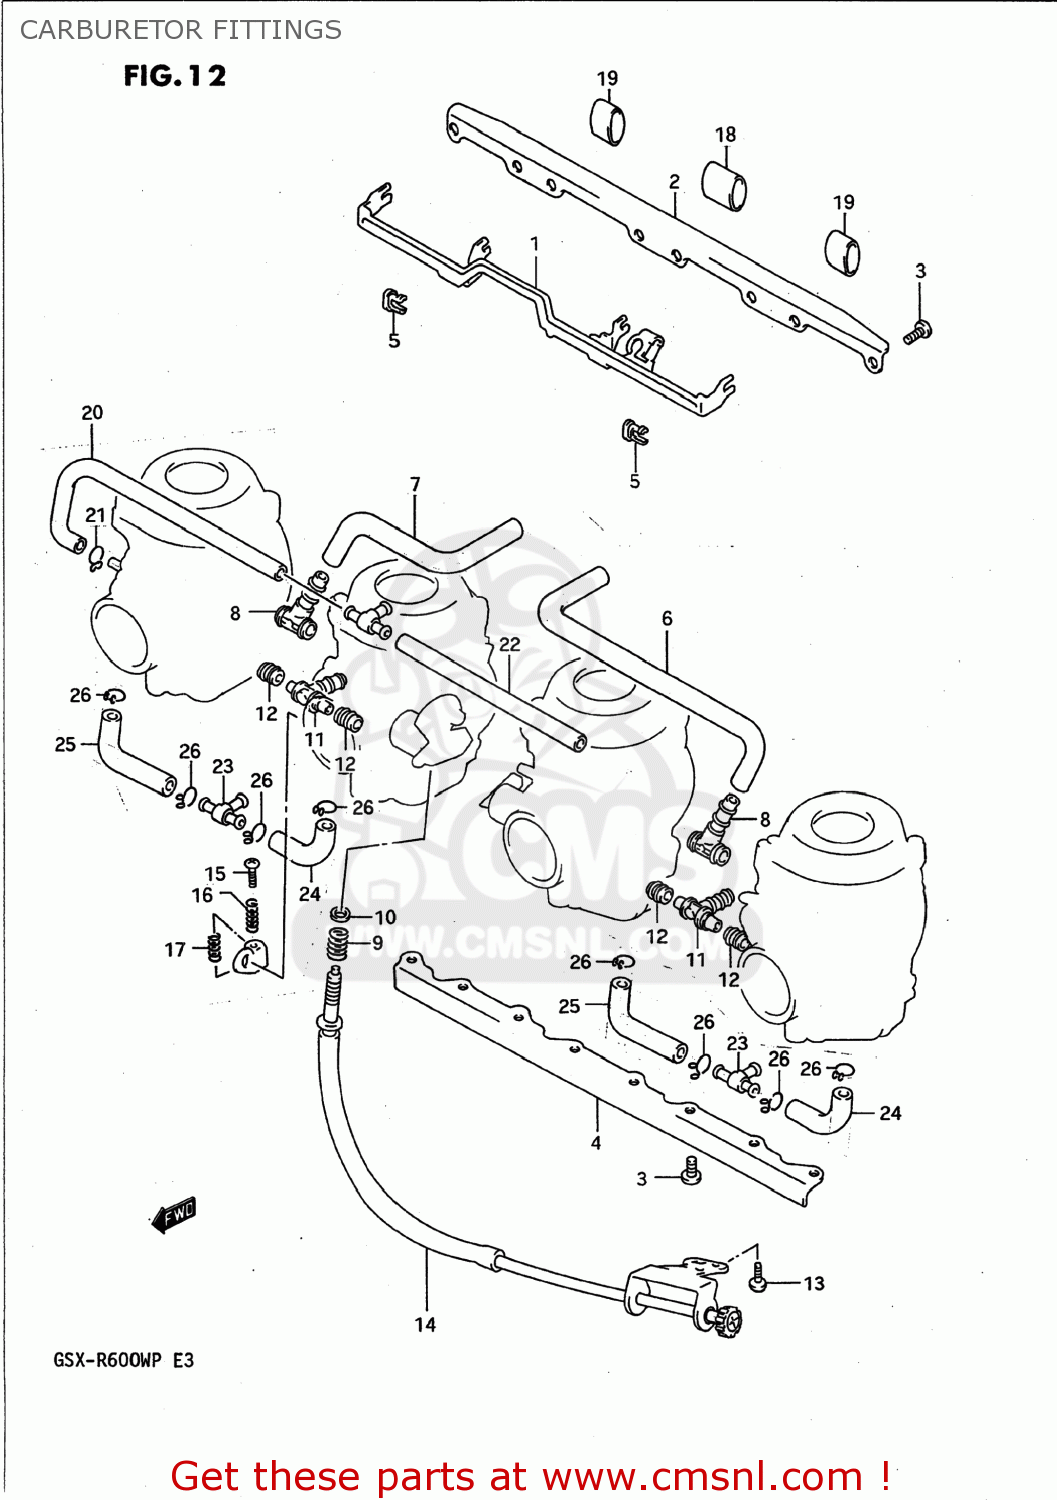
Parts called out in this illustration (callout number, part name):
1	LEVER,STARTER
2	PLATE
3	SCREW
4	PLATE
5	HOLDER
6	HOSE
7	HOSE
8	HOSE
9	SPRING
10	WASHER
11	NIPPLE
12	SEAL
13	SCREW
14	ADJUSTER ASSY
15	SCREW
16	SPRING
17	SPRING
18	HOSE
19	HOSE
20	HOSE
21	CLIP
22	HOSE
23	NIPPLE
24	HOSE
25	HOSE
26	CLIP
